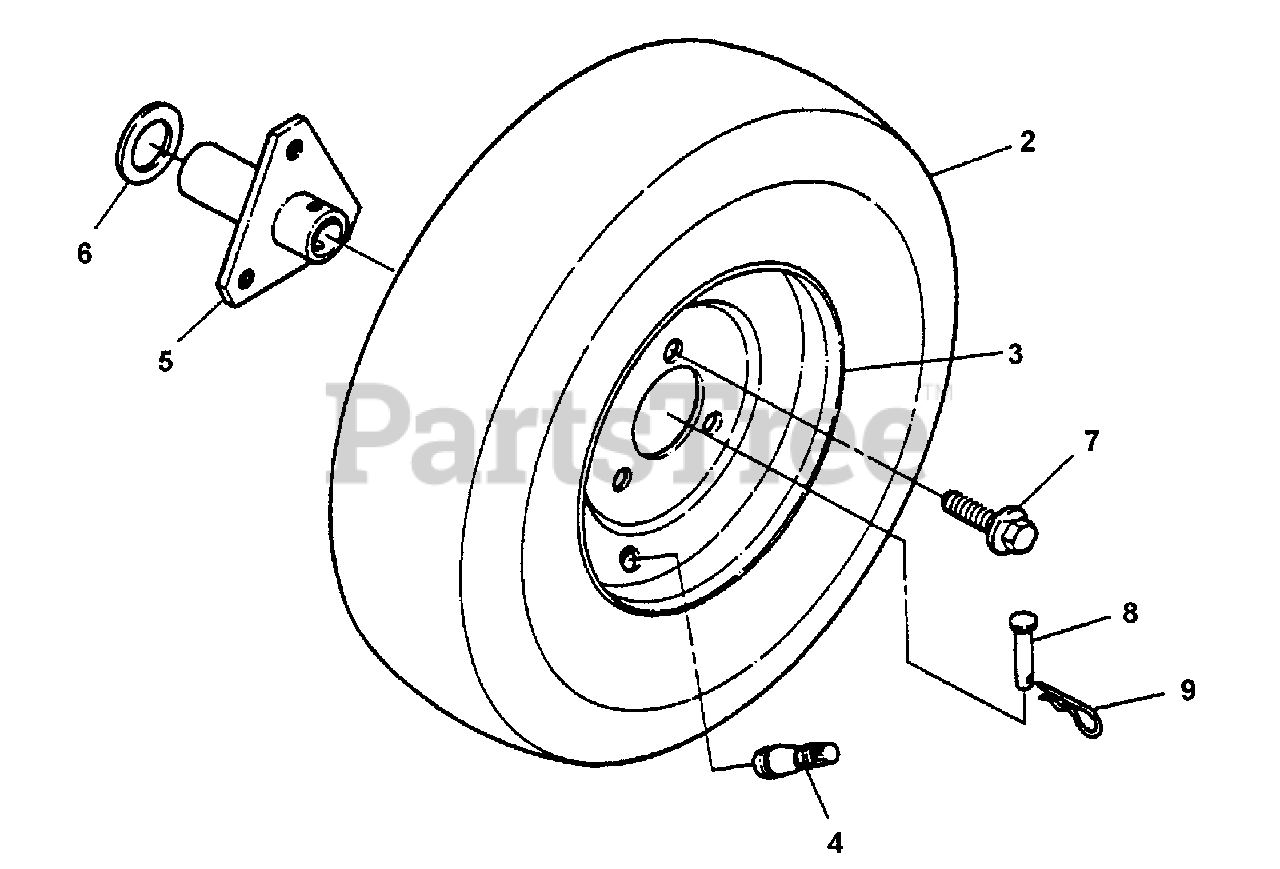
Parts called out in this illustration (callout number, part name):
2	TIRE, 16 x 4.80 x 8 (Snow Hog)(A)
2	TIRE, 16 x 6.50 x 8 (Snow Hog)(B)
2	* TIRE, 16 x 4.80 x 8 (Kenda)(C)
2	* TIRE, 16 x 6.50 x 8 (Kenda)(D)
3	RIM(A)
3	RIM(B)
4	VALVE, Snap-In
5	HUB, Wheel
6	WASHER, 3/4 x 1-1/8" Thrust
7	BOLT, 1/2-20 x 3/4" Hex Head Lug (Nyloc) Grade 5
8	PIN, 5/16 x1-11/16" Clevis
9	PIN, 3/32 x 1-1/2" Hair
